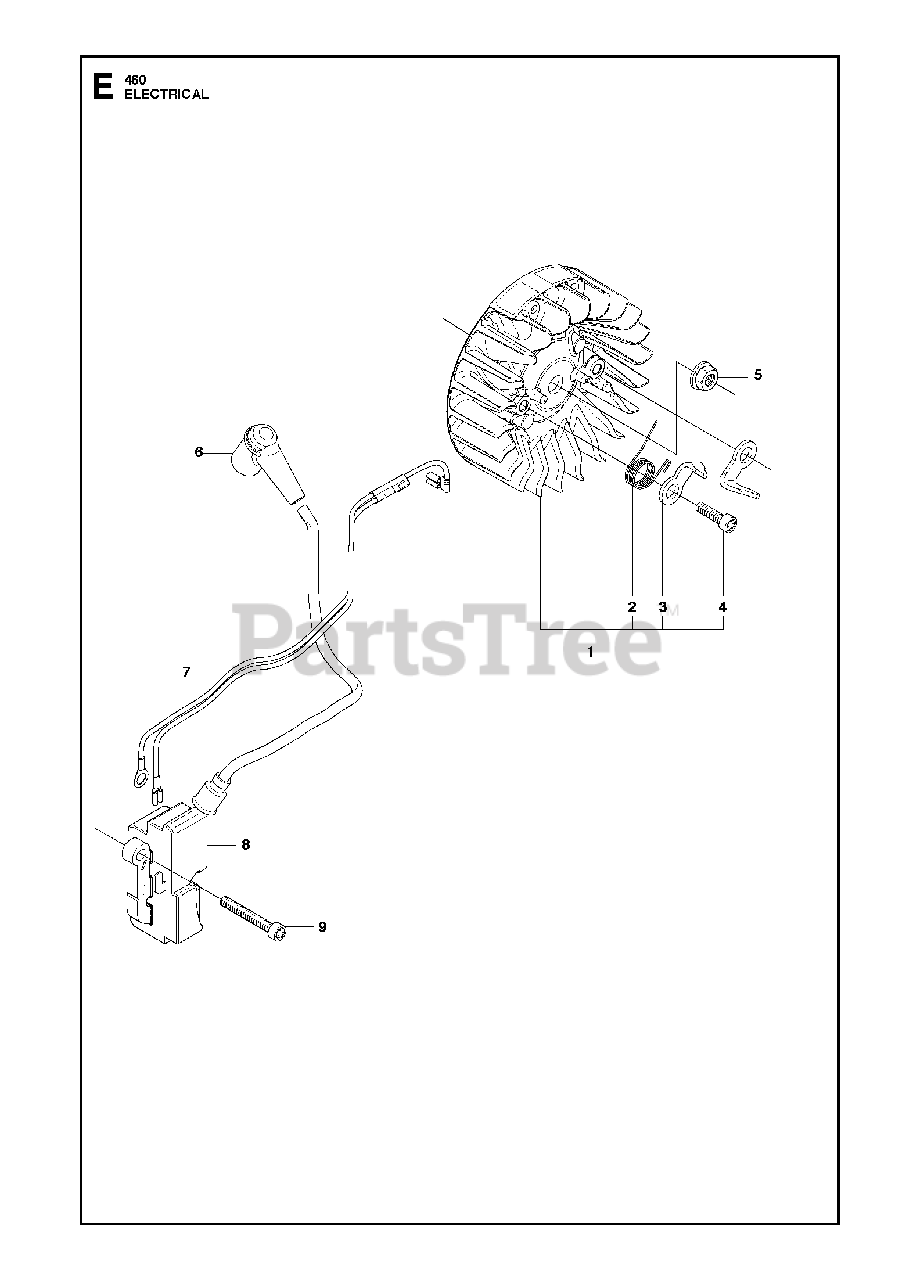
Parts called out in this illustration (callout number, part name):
2	SPRING
3	PAWL
4	SCREW
5	NUT W/ WASHER
6	SPARK PLUG CONN. KIT
7	CABLE ASSY
8	IGNITION MODULE
